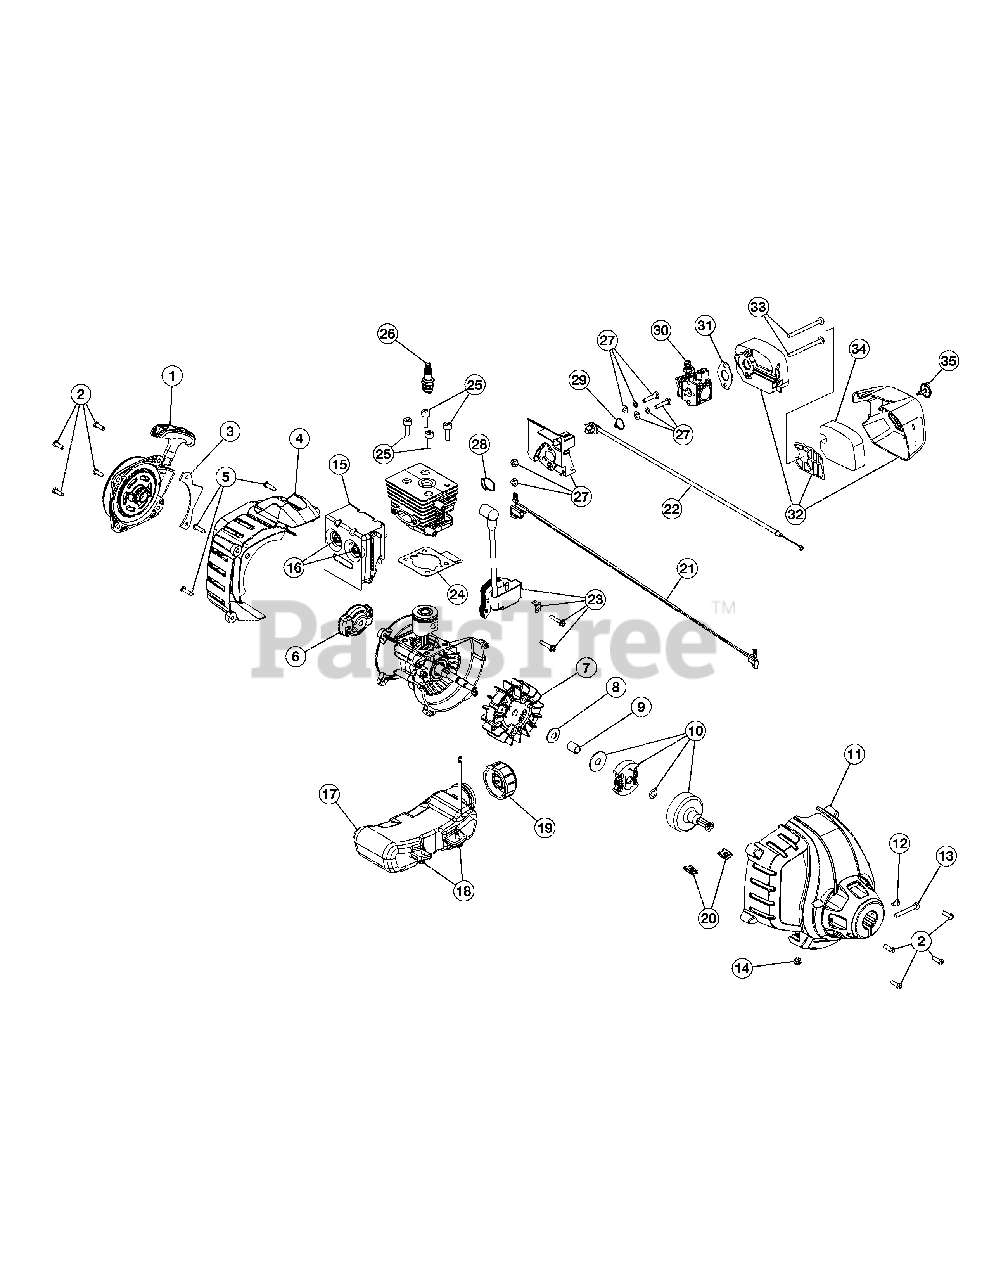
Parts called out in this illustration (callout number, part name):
1	Starter Assembly (Incl. 2 & 3)
2	Starter Screw
3	Starter Assembly Guard (Incl. 2)
4	Rear Engine Cover (Incl. 5)
5	Cover Screw
6	Pawl Assembly
7	Flywheel Assembly
10	Clutch Assembly
11	Clutch Cover Assembly (Incl. 2, 12 -14 & 21)
12	Anti-Rotation Screw
13	Clamp Screw
14	Clamp Nut
15	Muffler Assembly (Incl. 16)
16	Muffler Screw
17	Fuel Tank Assembly (Incl. 18 and 19)
20	U-shaped Nut
21	Lead Wires
22	Throttle Cable
23	Module Assembly
24	Cylinder Gasket
25	Cylinder Bolt
26	Spark Plug
27	Insulator Assembly (Incl. 28 and 29)
28	Insulator O-Ring
29	Carburetor O-Ring
30	Carburetor
31	Carburetor Gasket
32	Air Cleaner Assembly
34	Air Cleaner Filter
